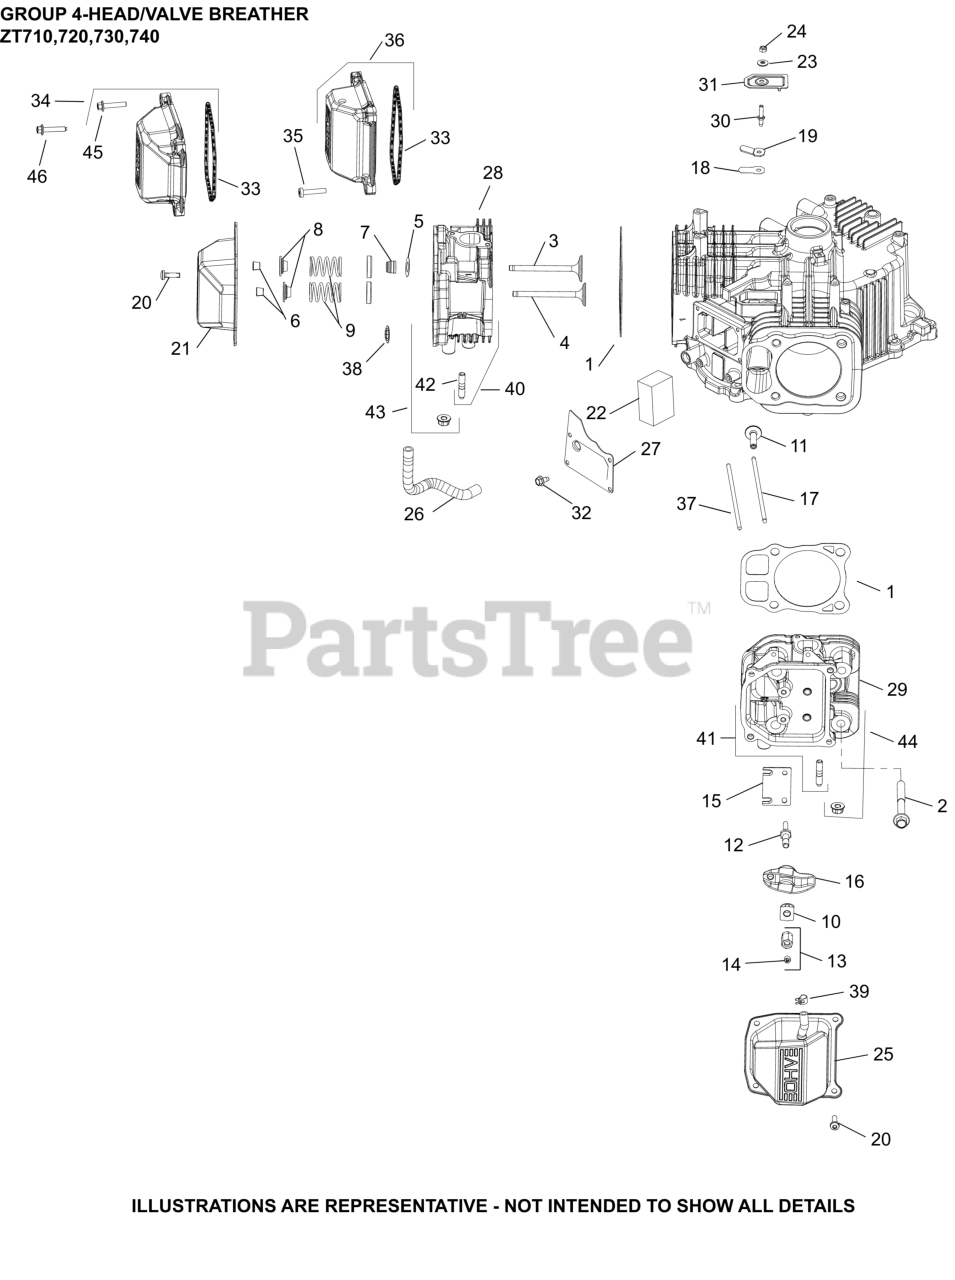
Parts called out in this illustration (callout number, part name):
1	KIT, GASKET CYLINDER HEAD
2	SCREW, HEX FLANGE M10 X 1.5-6g X 90mm
4	VALVE, EXHAUST
4	VALVE, EXHAUST (.25)
5	SPACER (.010")
6	KIT, RETAINER
7	SEAL, VALVE BAND
8	CAP, VALVE SPRING
9	SPRING VALVE
10	PIVOT, ROCKER ARM
12	STUD, ROCKER
13	HEX NUT ASSEMBLY
14	SCREW, SET
15	PLATE, GUIDE
16	ARM, ROCKER
17	ROD, PUSH
18	REED, BREATHER
19	RETAINER, REED
22	FILTER, BREATHER
23	WASHER, SEALING
24	NUT, LOCK M5X.8
26	HOSE, BREATHER
27	COVER, BREATHER MEDIA
31	COVER, BREATHER REED
32	SCREW, THREAD FORMING
33	O-RING (YELLOW), VALVE CO
34	KIT, VALVE COVER-PLAIN (PLASTIC)
36	KIT,BREATHER VALVE COVER (PLASTIC)
38	RETAINER, VALVE GUIDE (KM)
42	STUD, METRIC EXHAUST
43	KIT, CYLINDER HEAD #1
44	KIT, HEAD #2 AND HARDWARE-(#1675521S)
NI	VALVE, INTAKE (STD)
NI	VALVE, INTAKE (.25)-(#DSC)
NI	SCREW, HEX FLANGE (M6 X 31.625 DOG PT)
